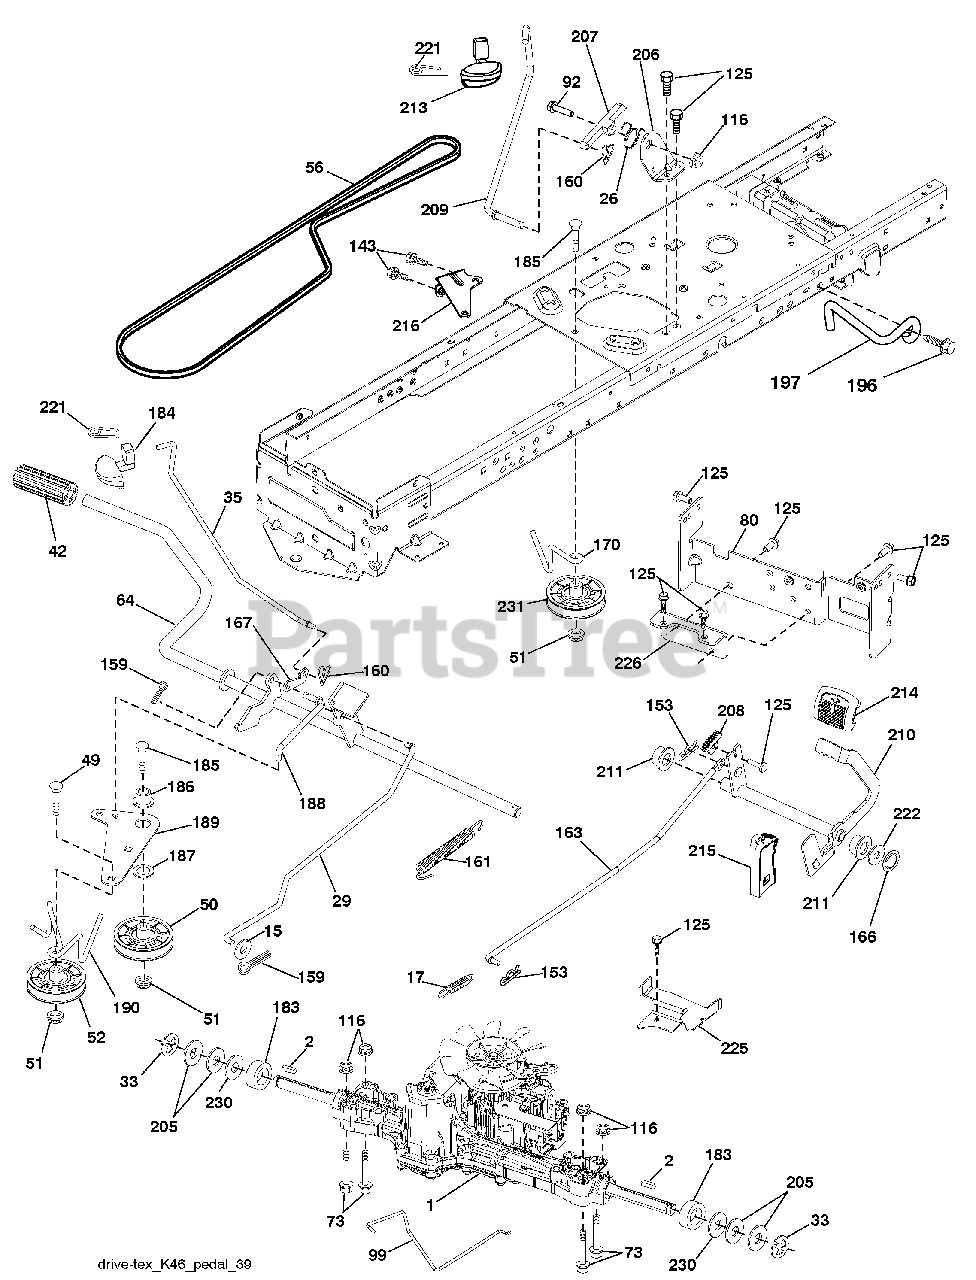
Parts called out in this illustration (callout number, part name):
1	Transaxle, Tufftorq K46BT
2	Key
15	Washer 13/32 x 13/16 x 16 Ga.
17	Spring, Brake
26	Spring Return Cruise
29	Rod, Brake
33	Ring E
35	Rod, Brake, Park
42	Cover, Foot Pedal
49	Bolt
50	Pulley Idler Flat
51	Lock Nut 3/8-16
52	Idler V-Groove 910" Offset
56	V-Belt, Drive
64	Shaft Asm. Pedal Brake Control
73	Bolt Hex 5/16-18 x 3.75
80	Strap Torque
92	Bolt Fin Hex 5/16-18 unc x 1.25
99	Rod Spring Bypass
116	Nut Lock Hex Flange 5/16-18
125	Screw 5/16-18 x 3/4
143	Screw 5/16-18 x 1/2
153	Retainer Spring
159	Pin Cotter 1/8 x 3/4
160	Retainer Clip
161	Spring, Return, Clutch
163	Rod Pedal Control
166	Nut Push .625
167	Latch Brake Parking
170	Keeper Belt Centerspan
183	Spacer Axle
184	Handle Parking Brake
185	Bolt
186	Spacer Retainer
187	Washer
188	Link Clutch Ground Drive
189	Bellcrank Ground Drive
190	Keeper Bellcrank Ground Drive
196	Screw 3/8-16 x 1
197	Link Clutch Anti-Rotation
205	Washer 25/32 x 1-5/8 x 16 Ga.
206	Bracket Mount Latch Cruise
207	Latch Control Cruise
208	Gear Sector Control Cruise
209	Rod Control Cruise
210	Rockr Asm. Pdeal Control
211	Bearing Nylon
213	Knob control Cruise
214	Pad Pedal Forward
215	Pad Pedal Reverse
216	Bracket Pulley Idler
221	Retainer Spring Clip Handle
222	Washer 21/32 x 1-1/4 10 Ga.
225	Keeper Belt Transaxle
226	Bracket Mount Torque
230	Washer Harden .793 x 1.637 x 060
231	Idler V-Groove
